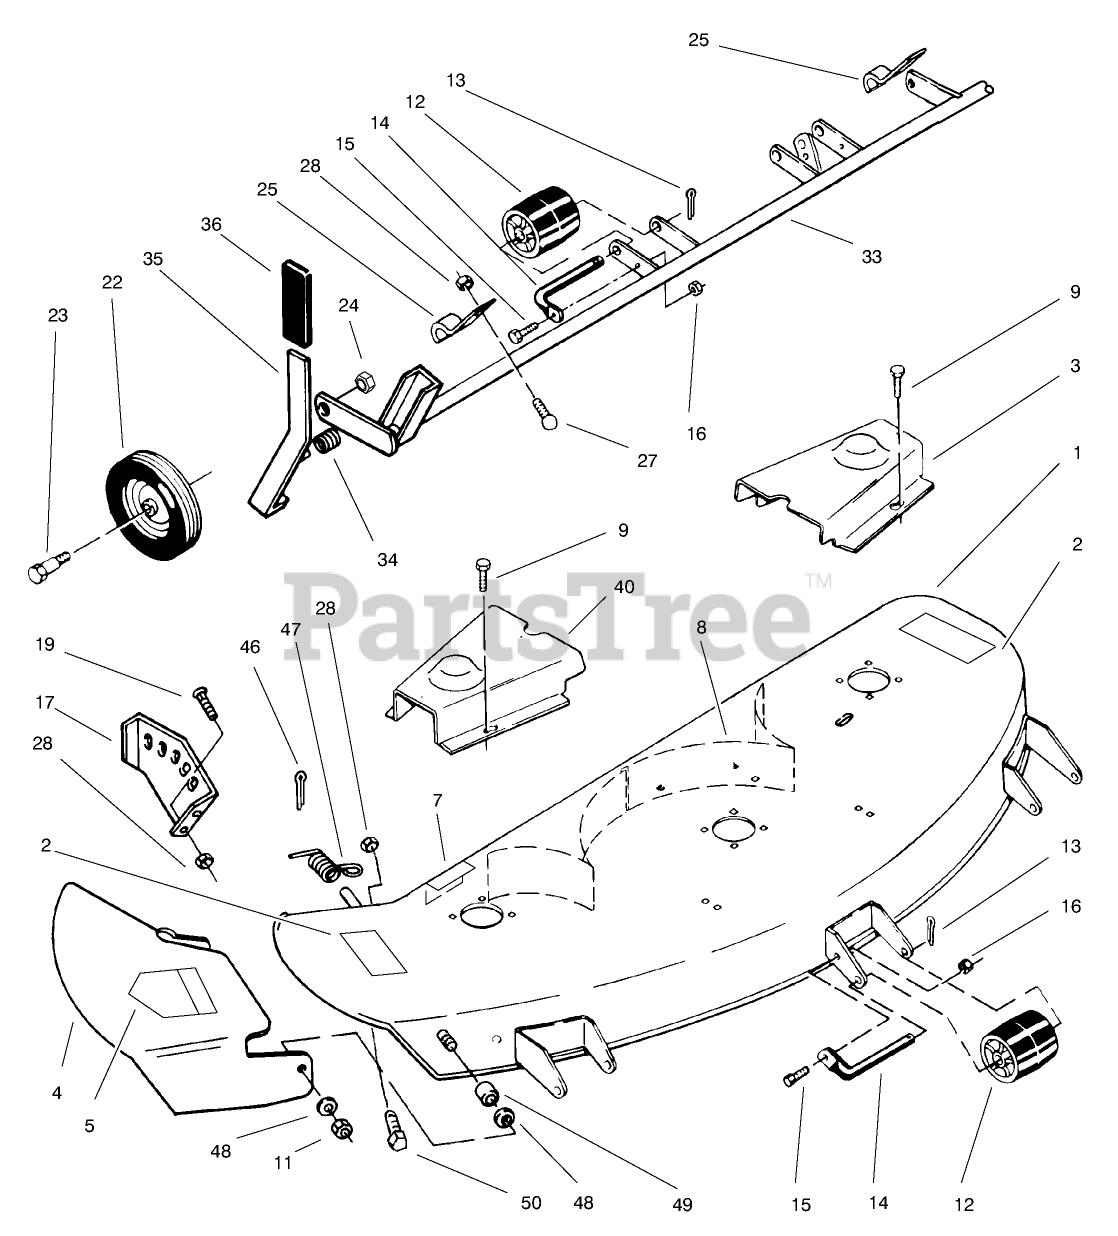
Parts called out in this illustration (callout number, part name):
1	Deck-Assembly (Incl. Ref. #2 & 8)
2	DECAL-DANGER
3	COVER-BLADE (RED)
4	Chute Assembly (Incl. Ref. #5)
5	DECAL-DANGER
7	DECAL-HEIGHT & BELT
8	BAFFLE-DECK R.H.
9	SCREW-HWH
11	NUT-HJ
12	ROLLER
13	PIN-COTTER
14	Shaft-Roller
15	SCREW-HH
16	NUT-LOCK, NI
17	RH QUADRANT (RED)
19	BOLT-CARR
22	WHEEL
23	BOLT-SHOULDER
24	NUT-HEX
25	BRACKET-PIVOT
27	BOLT-CARR
28	NUT-LOCK, NI
33	WA-SUPPORT, GAGE WHL (RED)
34	SPRING-COMPRESSION
35	WELDMENT-LEVER (RED)
40	COVER-BELT, RH
46	PIN-COTTER
47	SPRING-DEFLECTOR
48	WASHER
49	BUSHING-PIVOT
50	SCREW-HH
